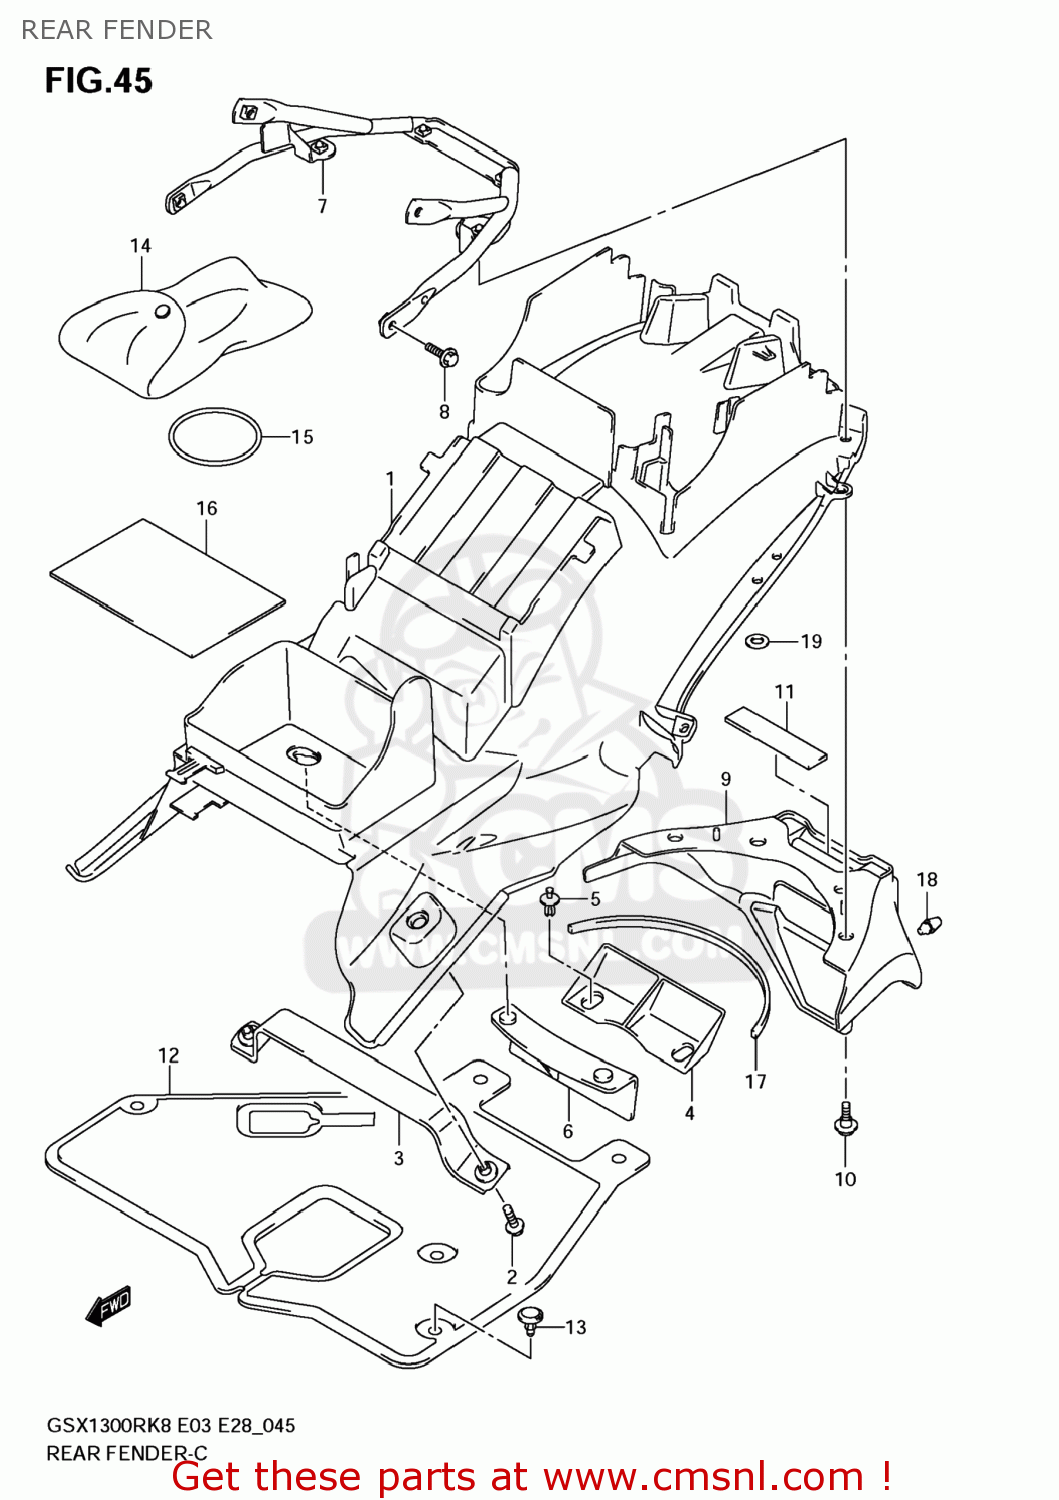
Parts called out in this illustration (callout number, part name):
1	FENDER,RR FR
2	BOLT
3	BRACKET,RR FENDER FR
4	MUDGUARD,RR FENDER
5	CLIP
6	MUDGUARD,RR FENDER FR UPR
7	BRACKET,RR FENDER
8	BOLT
9	FENDER,RR RR
10	BOLT(6X16)
11	PROTECTOR(20X90)X4
12	SHIELD,INNER
13	CLIP
14	TOOL ASSY
15	O RING(D:3.5,ID:61)
16	CUSHION,RR FENDER FR
17	CUSHION,RR FENDER RR
18	CUSHION
19	WASHER(6.5X14X2)
